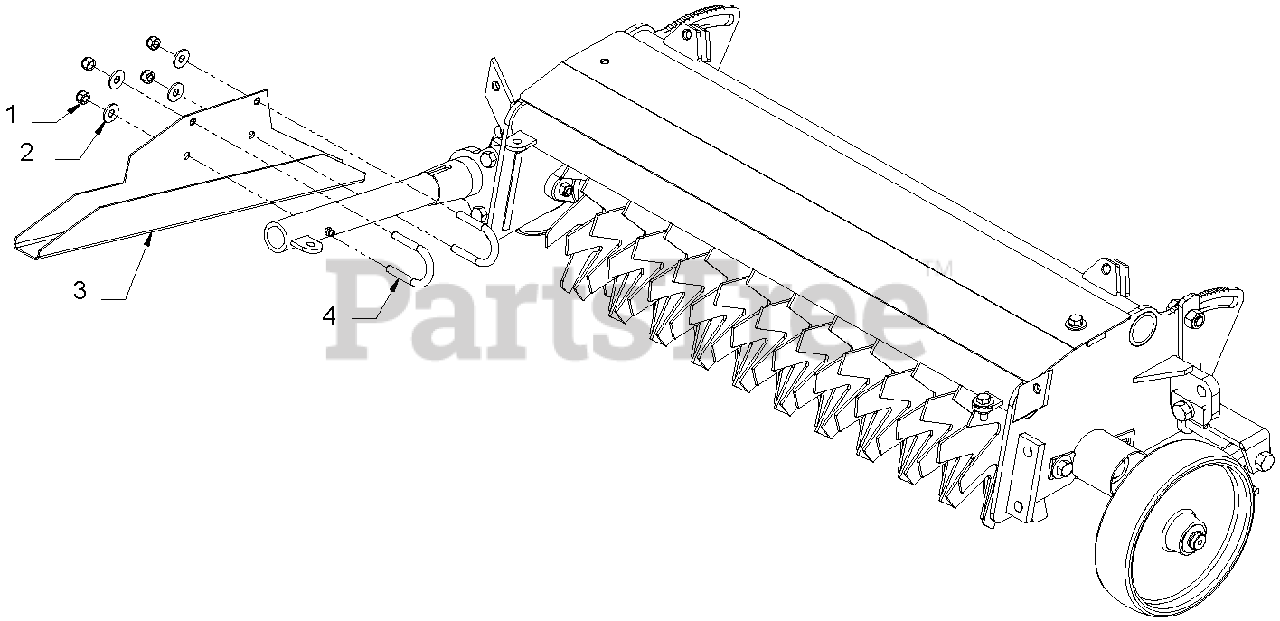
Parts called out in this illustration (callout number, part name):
1	Nut, Hex 5/16-18 Nyloc CP
2	Washer, Flat 5/16 SAE Hard YZ
3	Guard, Verticutter Telescoping Arm
4	U-Bolt, 5/16-18 x 1-3/8 x 2-3/16
